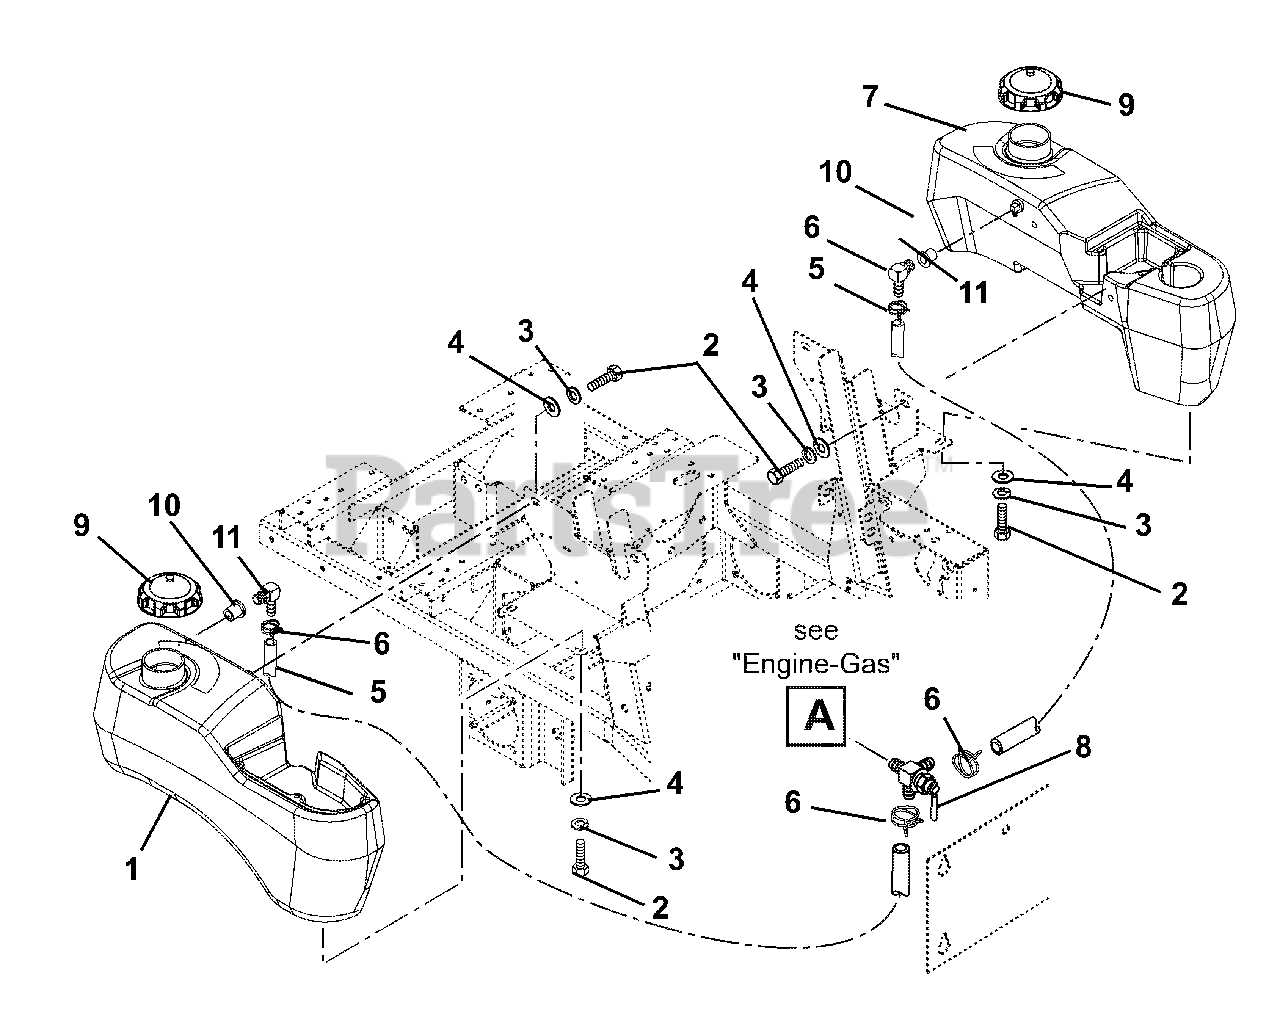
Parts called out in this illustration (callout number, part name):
1	Tank, Gas Fuel-Right Hand
2	Bolt, Hex .31-18 x .75 Grade 5
3	Washer, Locking .31 x .078
4	Washer, Flat Steel .38 x .875 x .083
5	Gas Line-Bulk .25 I.D.
6	Clamp, Hose Wire .49/.51 x .116
7	Tank, Left Hand Fuel (EYE-Q) 200 Series
8	Valve, Fuel
9	Cap, Gas
11	Fitting, Tank
